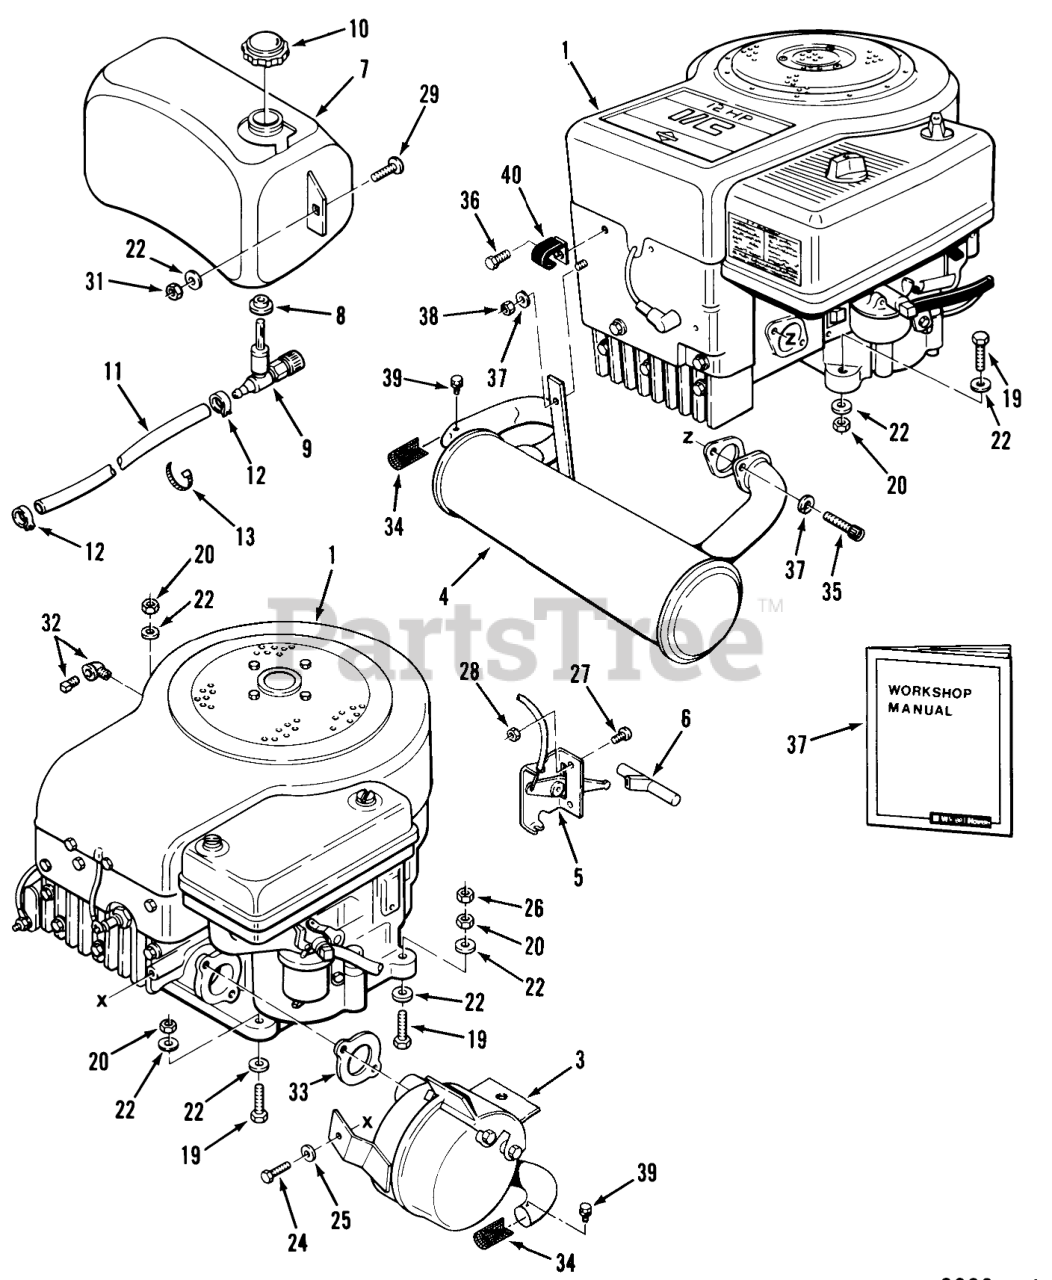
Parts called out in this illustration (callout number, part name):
1	Engine-11HP-BS Model 253707, Type 0222-01 211-5 Only
3	MUFFLER
10	CAP GAS
22	WASHER 5/16 SAE
32	STREET ELBOW 45DEGRE
35	SHCS 5/16-18X.625
